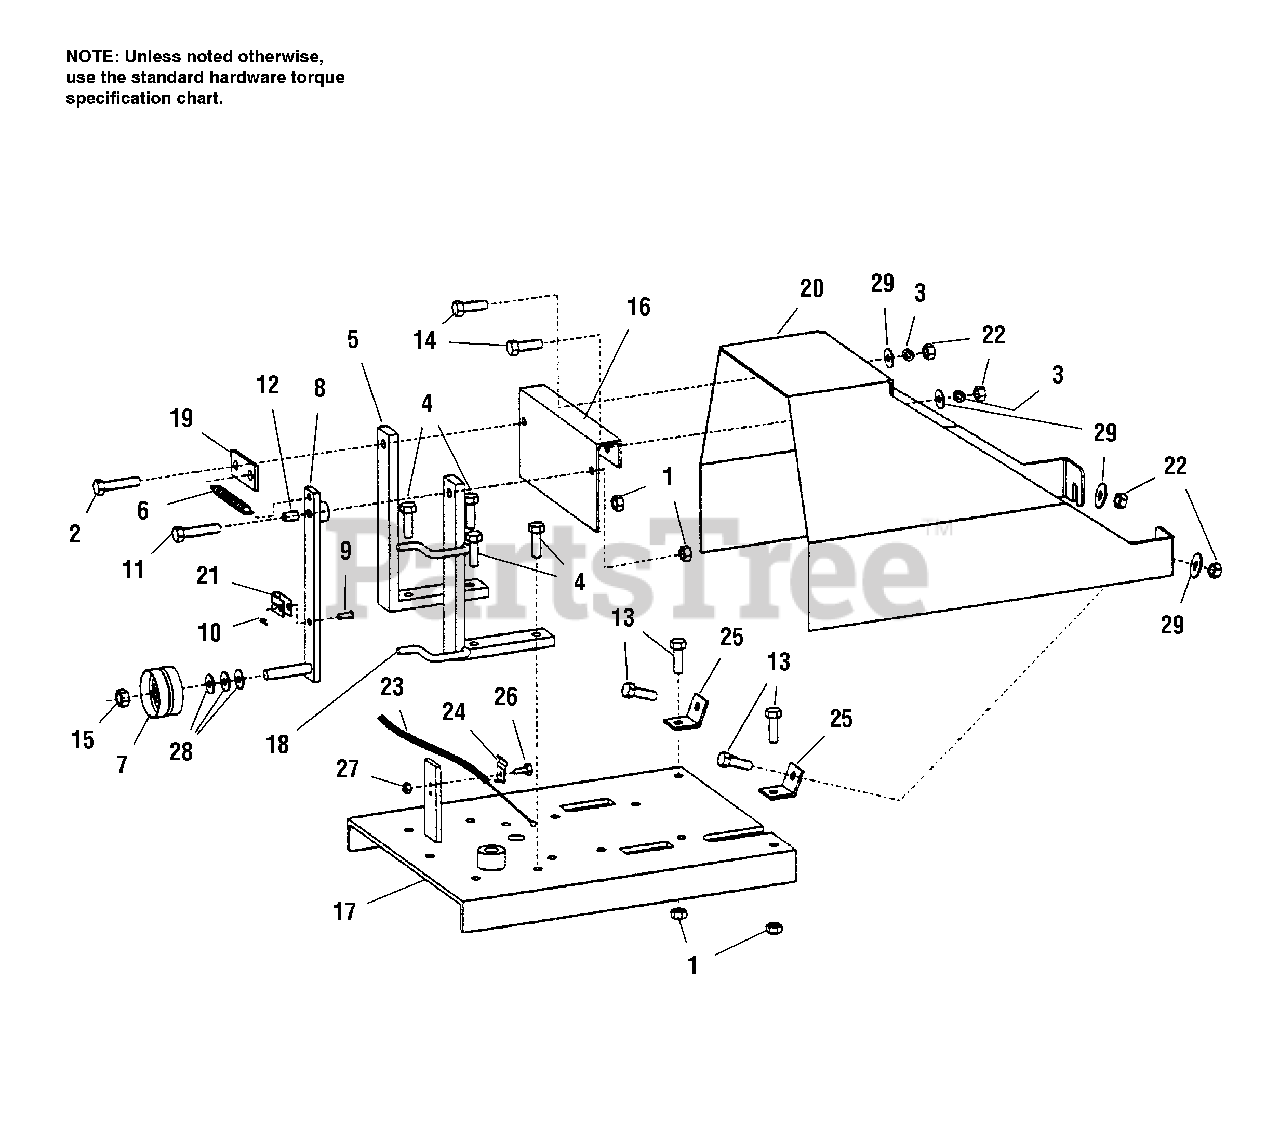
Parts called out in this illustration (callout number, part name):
1	NUT-Bi-Way Lock, 5/16-18
2	BOLT-Hex Hd, 5/16-18 x 1-1/2", Grade 5
3	LOCKWASHER-Spring, 5/16"
4	BOLT-Hex Hd, 5/16"-18 x 1-1/4", Grade 5
5	MOUNTING BAR-Shift Mechanism
6	SPRING-Idler Arm
7	PULLEY-Forward Idler
8	IDLER ARM-Forward
9	LINK PIN-Forward
11	CAPSCREW, Hex Head 5/16-18 x 2 G5
12	BUSHING-Pivot, 5/16"
13	BOLT-Hex Flange Hd, 5/16-18 x 3/4", Grade 5
14	BOLT-Hex Hd, 5/16-18 x 3/4"
15	NUT-Hex, 3/8-16
16	SUPPORT BRACKET-Belt Cover
17	COVER-Transmission Wheel Housing
18	MOUNTING BAR-Shift Mechanism, w/Forward Belt Guides
19	PLATE-Shift Mech Mounting Bar
22	NUT-Non Locking, 5/16-18
23	CABLE ASSEMBLY-Drive Control Lever
24	C-CLAMP, Drive Control Cable
25	MOUNTING BRACKET-Belt Cover
26	BOLT-Hex Hd, 5mm x 0.8mm x 10mm
27	NUT-Nyloc, 5mm x 0.8mm
28	WASHER-Flat, 3/8"
29	WASHER-Flat, 5/16"
